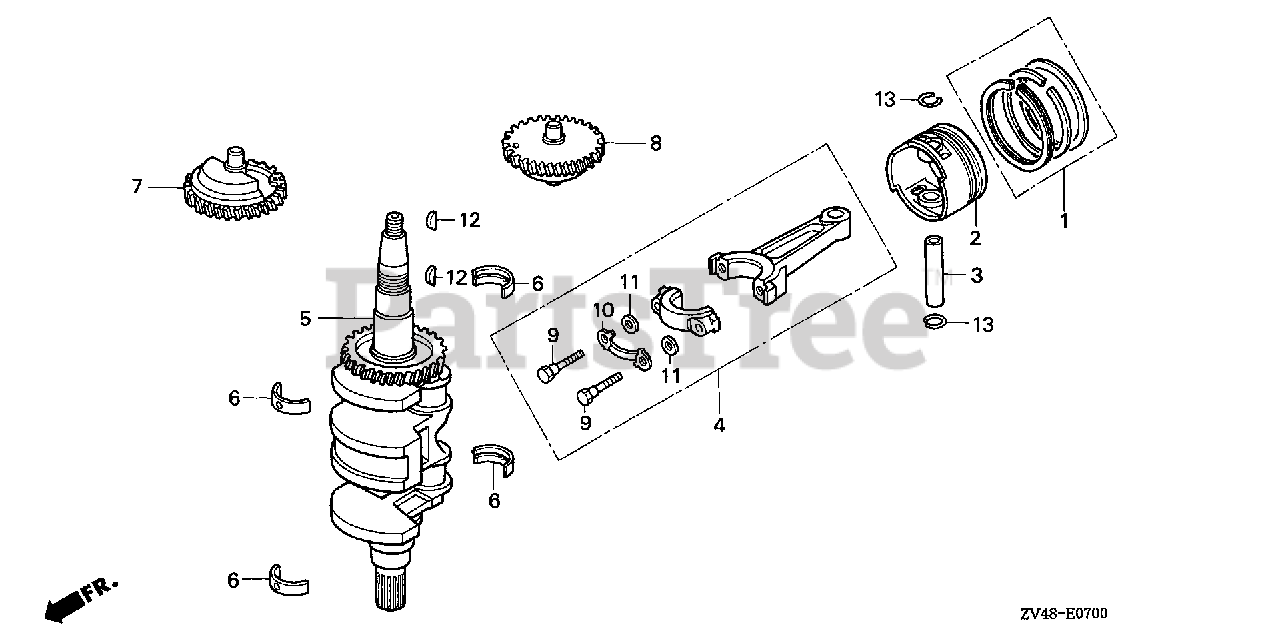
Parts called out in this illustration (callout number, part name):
1	RING SET, PISTON (STD)
3	PIN, PISTON
4	ROD ASSY., CONNECTING
5	CRANKSHAFT
6	BEARING, CRANKSHAFT (BLACK)
6	BEARING, CRANKSHAFT (BROWN)
6	BEARING, CRANKSHAFT (GREEN)
6	BEARING, CRANKSHAFT (YELLOW)
6	BEARING, CRANKSHAFT (RED)
7	WEIGHT A, BALANCER
8	WEIGHT B, BALANCER
9	BOLT, CONNECTING ROD
10	WASHER, TONGUED
11	WASHER, PLAIN (7MM)
12	KEY, SPECIAL (16X15)
13	CLIP, PISTON PIN (14MM)
